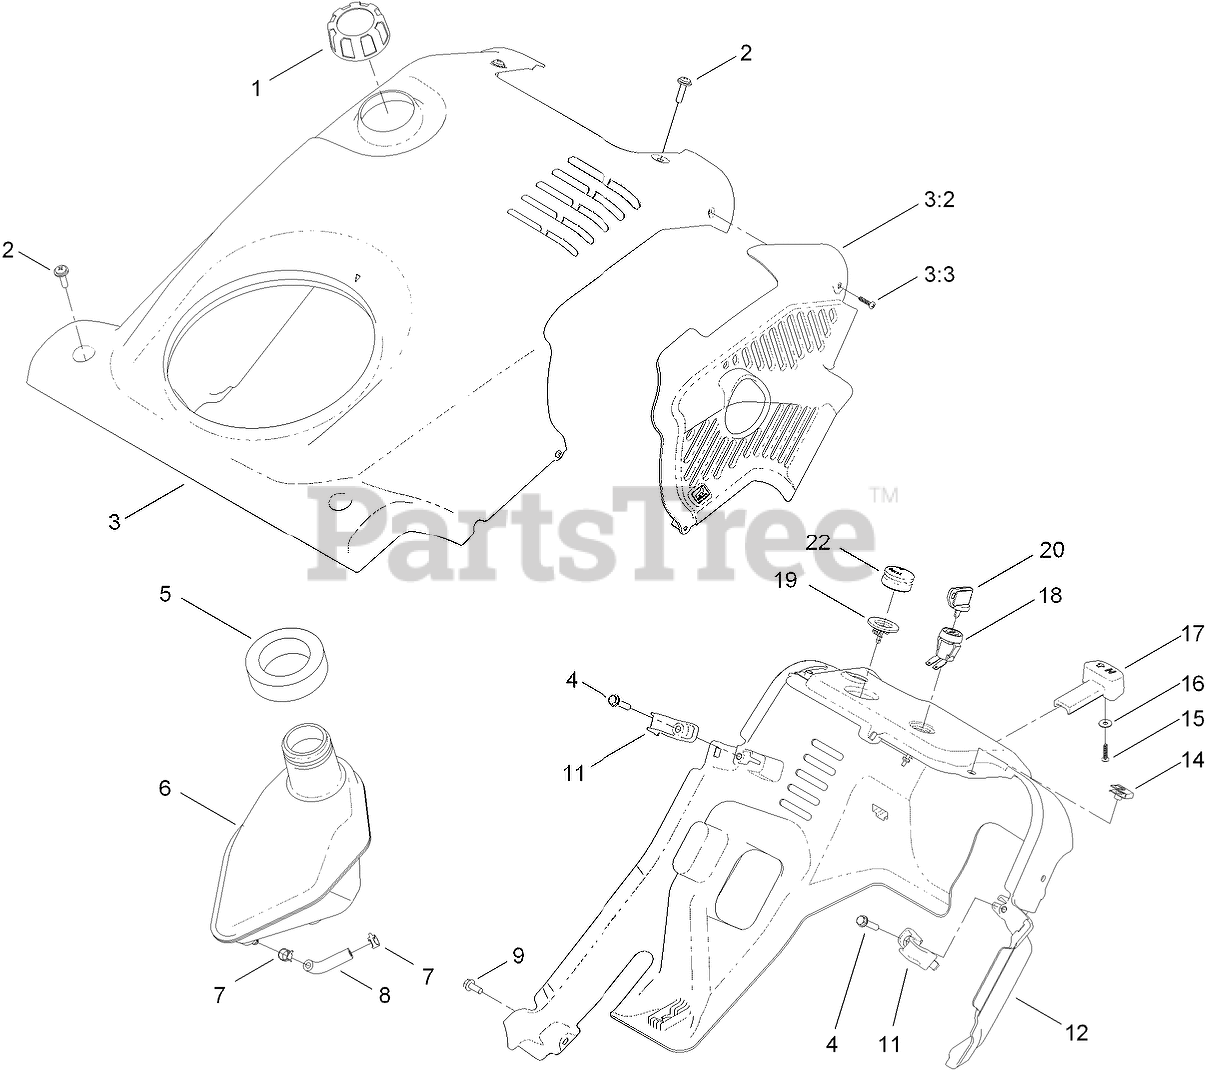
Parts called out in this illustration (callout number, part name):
1	4-CYCLE GAS CAP ASM
2	SCREW-PPH
3	SHROUD ASM
3:2	BAFFLE-EXHAUST
3:3	SCREW-PPH
4	SCREW-PLASTITE
5	SEAL-TANK
6	TANK-FUEL, GAS
7	CLAMP-HOSE
8	HOSE-FUEL
9	SCREW-HWH
11	CLIP-SHROUD
12	SHROUD-LOWER
15	SCREW-PPH
16	WASHER-PLAIN
17	KNOB-CHOKE
18	SWITCH
19	BODY-PRIMER
20	KEY-IGNITION
22	BULB-PRIMER
